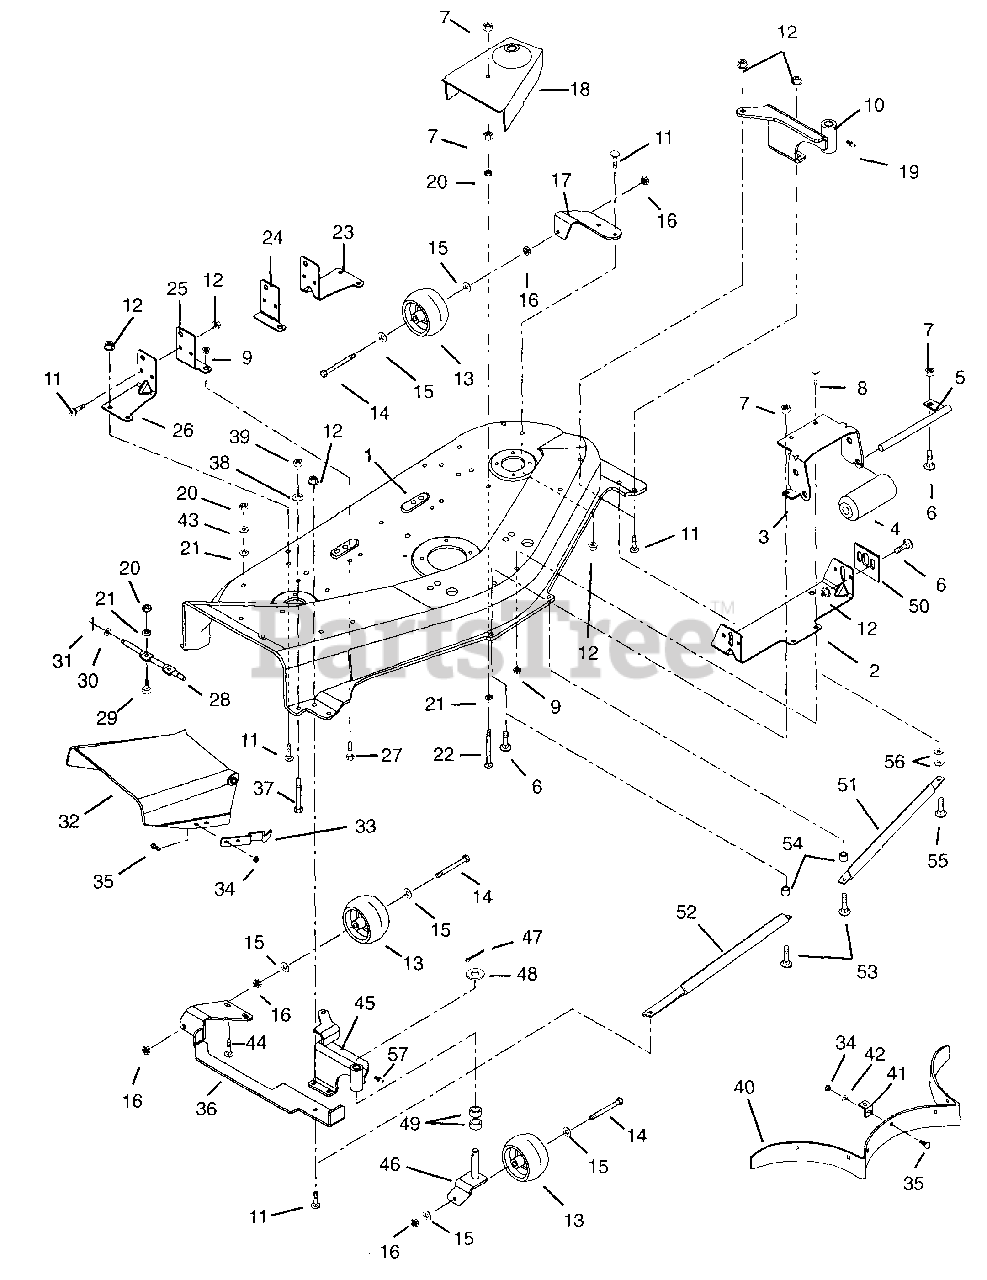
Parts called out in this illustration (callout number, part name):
1	MOWER PAN W/DECALS 48"- ORANGE
2	FRONT HANGER
3	BRACKET, ROLLER
5	ROLLER SHAFT
6	@BLT-RDHDSQNK .31-18X.75 G5YZ
7	@NUT-LK-CTR .31-18 YWZC
8	BLT-RDHDSQNK .50-13X.75 SHT PL
9	@NUT-LK-CTR .50-13 YWZC
10	WELDMENT-LEFT FRONT
11	BLT-RDHDSQSHK.31-18X.75 GR2 YW
12	@NUT-SPNLK-FLG .312-18 YWZC
14	@BLT-HEX .38-16X3.50 GR5 YWZC
15	@WSHR-FL-STL.38X.875X.083 YWZC
16	@NUT-LK-CTR .38-16 YWZC
17	BRACKET-LEFT REAR
18	R.H. BELT GUARD
18	L.H. BELT GUARD
19	FTG-LUBE .25-28X.256 YWZC
20	@NUT-HEX .31-18 YWZC
21	WSHR-LK .312X.097 HVY YWZC
22	BLT-RDHDSQNK .31-18X3.25 SHTPL
23	LH REAR HANGER
24	LH REAR HANGER SUPPORT
25	RH REAR HANGER SUPPORT
26	RH REAR HANGER
27	@BLT-HEX .50-13X1.00 GR5 YWZC
28	HINGE PIN
29	@BLT-HEX .31-18X.75 GR5 YWZC
30	@WSHR-FL-STL.406X.812X.065 YWZ
31	@PIN-CTR .09X.75 EXTPRSQCT YWZ
32	CHUTE EXTENSION
33	SPRING, FLAT
34	@NUT-LK-CTR .25-20 YWZC
35	BLT-RDHDSQSHNK.25-20X.50 YWZC
36	WELDMENT-RIGHT REAR
37	@BLT-HEX .38-16X2.50 GR5 YWZC
38	WSHR-LK .375X.115 HVY YWZC
39	@NUT-HEX .38-16 YWZC
40	BAFFLE
41	BAFFLE TAB
42	@WSHR-FL-STL.281X.62X.065 YWZC
43	@WSHR-FL-STL.312X.734X.065 YWZ
44	@BLT-RDHDSQNK .31-18X1.00 G5YZ
45	WELDMENT-RIGHT FRONT
46	CASTER FORK, WELDMENT
47	@PIN-CTR .18X1.25 EXTPRSQCT YZ
48	WSHR-FL-STL .630X1.005X.062 YZ
49	BSHG-SLV .625X.750X.500 BR
50	MOWER ADJUSTMENT TAB
51	GUARD - FOOT - LH
52	GUARD - FOOT - RH
53	@BLT-RDHDSQNK .31-18X1.50 G5YZ
54	SPACER .375 X .625 X .500
55	@BLT-RDHDSQNK .31-18X1.25 G5YZ
56	WSHR-FL-STL .390X.75X.125 YWZC
